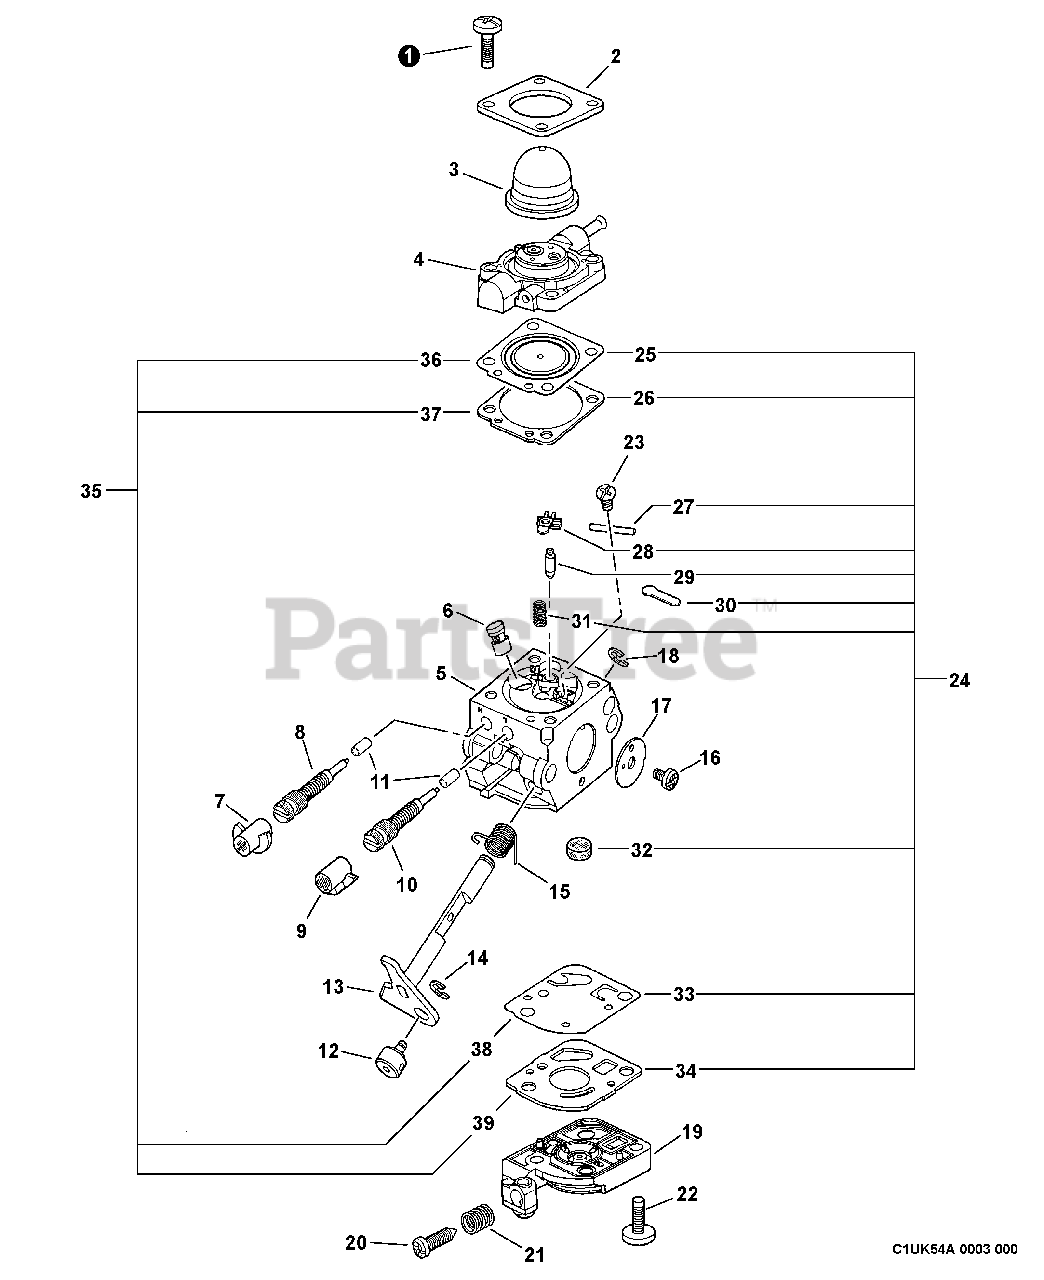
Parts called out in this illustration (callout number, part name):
2	RETAINER, PURGE BULB
3	BULB, PURGE
4	BODY ASSY, PURGE
5	BODY, CARBURETOR
6	NOZZLE, CHECK VALVE
7	CAP, LIMITER - RED
8	NEEDLE, HIGH SPEED
9	CAP, LIMITER - WHITE
10	NEEDLE, MIXTURE
11	RETAINER
13	SHAFT ASSY, THROTTLE
15	SPRING, THROTTLE RETURN
17	VALVE, THROTTLE
19	COVER, FUEL PUMP
20	SCREW, THROTTLE ADJUST
24	REBUILD KIT
25	DIAPHRAGM, METERING
26	GASKET, METERING
27	PIN, METERING LEVER
28	LEVER, METERING
29	VALVE, INLET NEEDLE
30	PLUG, WELCH
31	SPRING, METERING LEVER
32	STRAINER
33	DIAPHRAGM, PUMP
34	GASKET, PUMP
35	GASKET / DIAPHRAGM KIT
36	DIAPHRAGM, METERING
37	GASKET, METERING
38	DIAPHRAGM, PUMP
39	GASKET, PUMP
